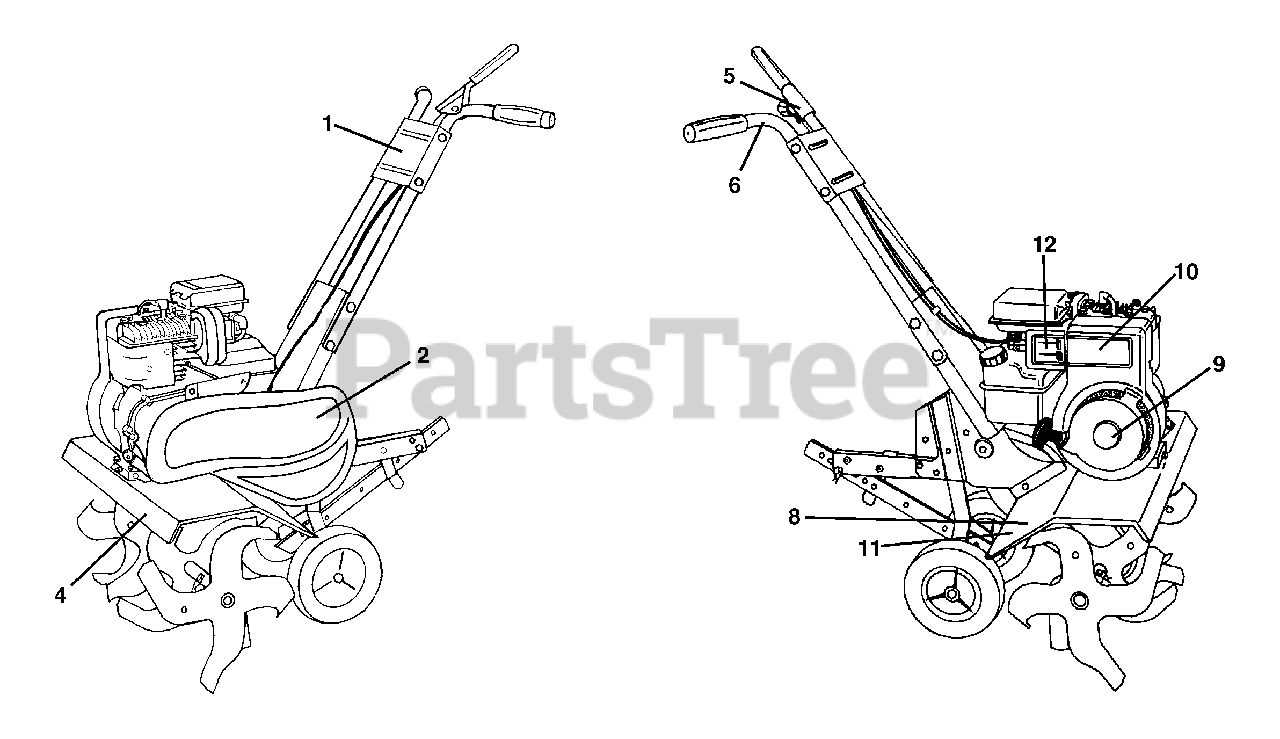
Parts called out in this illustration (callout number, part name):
1	Decal, Control Panel (Statesman)
1	Decal, Control Panel (Agway)
2	Decal, Belt Guard (Statesman)
2	Decal, Belt Guard (Agway)
4	Decal, Description
5	Decal, Tine Control
6	Decal, Hand Placement
8	Decal, Warning, Rotating Tines
9	Decal, Briggs & Stratton
10	Decal, 3.5 HP
11	Decal, Warning
12	Decal, Speed Control
